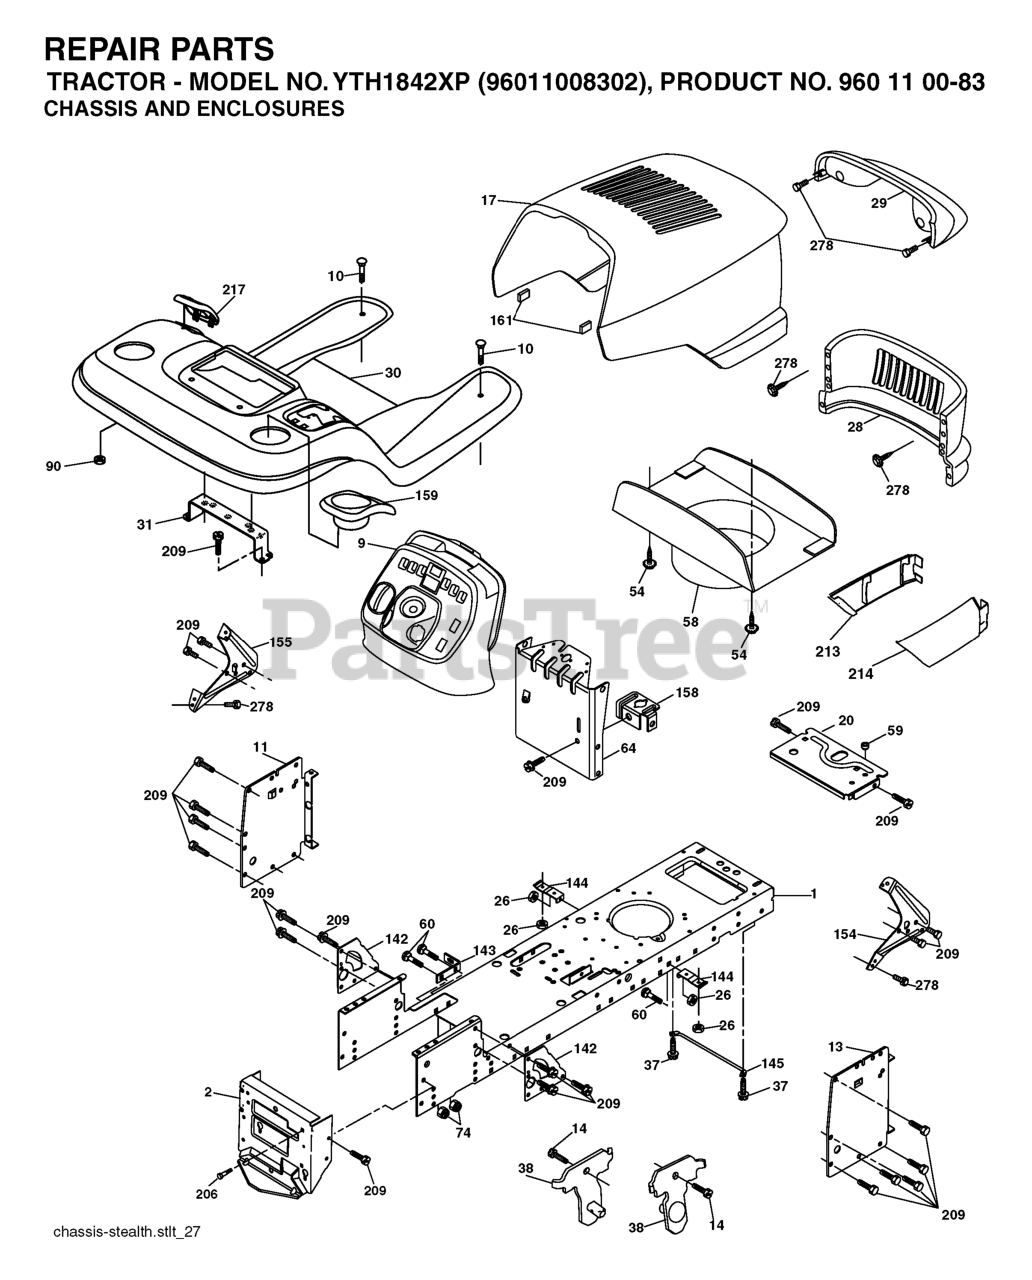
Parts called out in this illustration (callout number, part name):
1	AUGER.PLENUM.SINGLE.STAGE.GREY
2	COVER NON-DRIVE SIDE HUSQ ST1
3	COVER.DRIVE.SIDE.HUSQ.GY.ST111
4	WASHER
5	BOLT.HEX.HD.WASHER.5/16-18X.75
6	SCREW.HX.13X.750
8	SCREW.PAN.HD.TORX.1/4-20X.750
9	SCREW.1/4-20.PAN.HEAD.TORX.
10	PLATE.EXHAUST.SINGLE.STAGE.SNO
